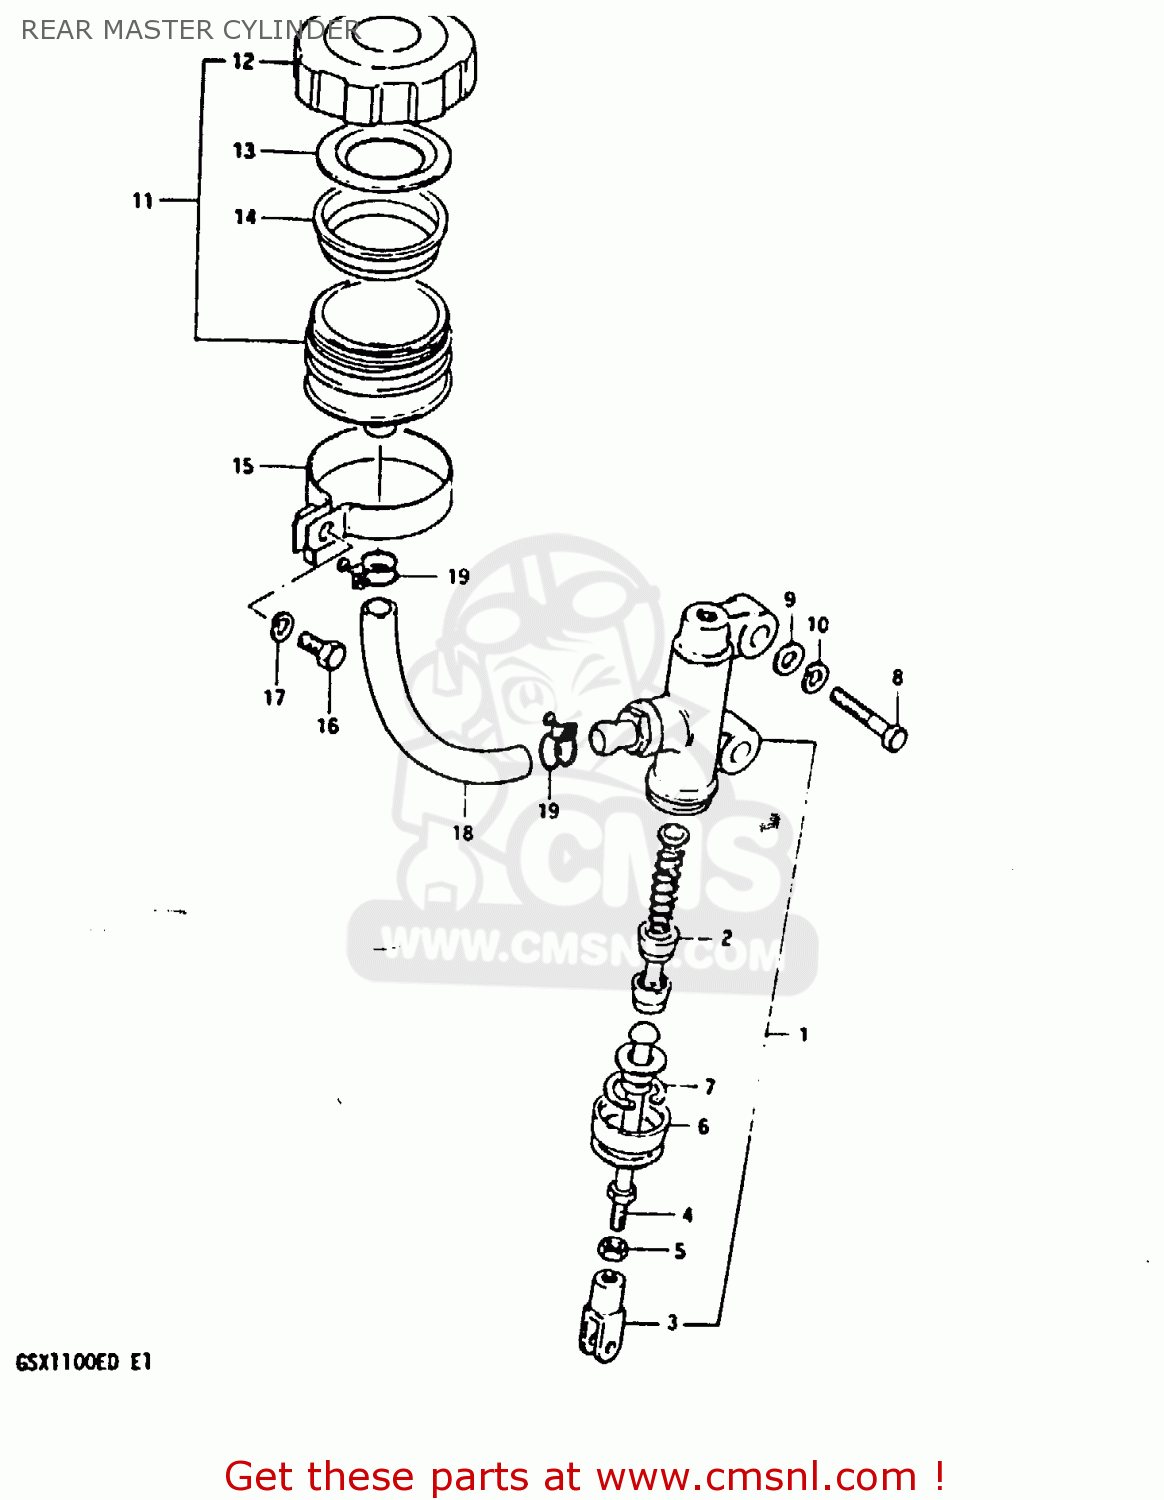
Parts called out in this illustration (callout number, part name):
1	CYLINDER ASSEMBLY,REAR MASTER
2	PISTON/CUP SET
3	YOKE
4	ROD,PUSH
5	NUT,MASTER CYLINDER
6	BOOT
7	CIRCLIP
8	BOLT (8X30)
9	WASHER
10	LOCK WASHER
11	TANK ASSEMBLY,RESERVOIR
12	CAP
13	PLATE,DIAPHRAGM
14	DIAPHRAGM
15	CLAMP
16	BOLT, UPPER
17	LOCK WASHER
18	HOSE,RESERVOIR TANK
19	CLAMP
